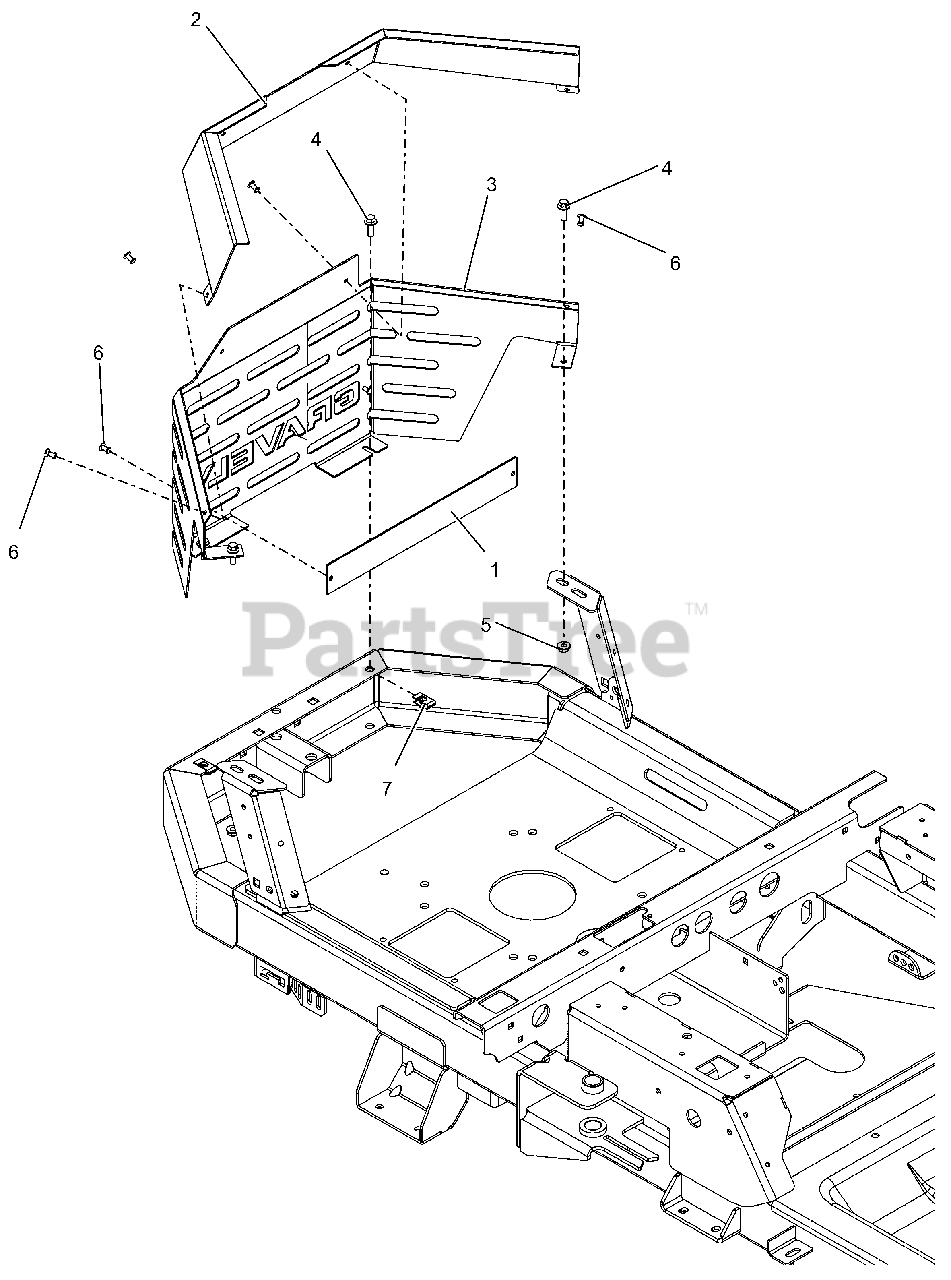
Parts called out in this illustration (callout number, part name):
1	PLATE, SHROUD BACKER
2	WLDMT, ENGINE SHROUD TRIM-XL
3	SHROUD, ENGINE - GRAVELY XL
4	BLT,HEX-FLG .25-20X.75 G5 BFP
5	NUT-LK-TOP-FLG .250-20 GF ZCC
6	RIVET, #66 STEEL POP PD BLACK
7	NUT-RTNR .25-20X.56
